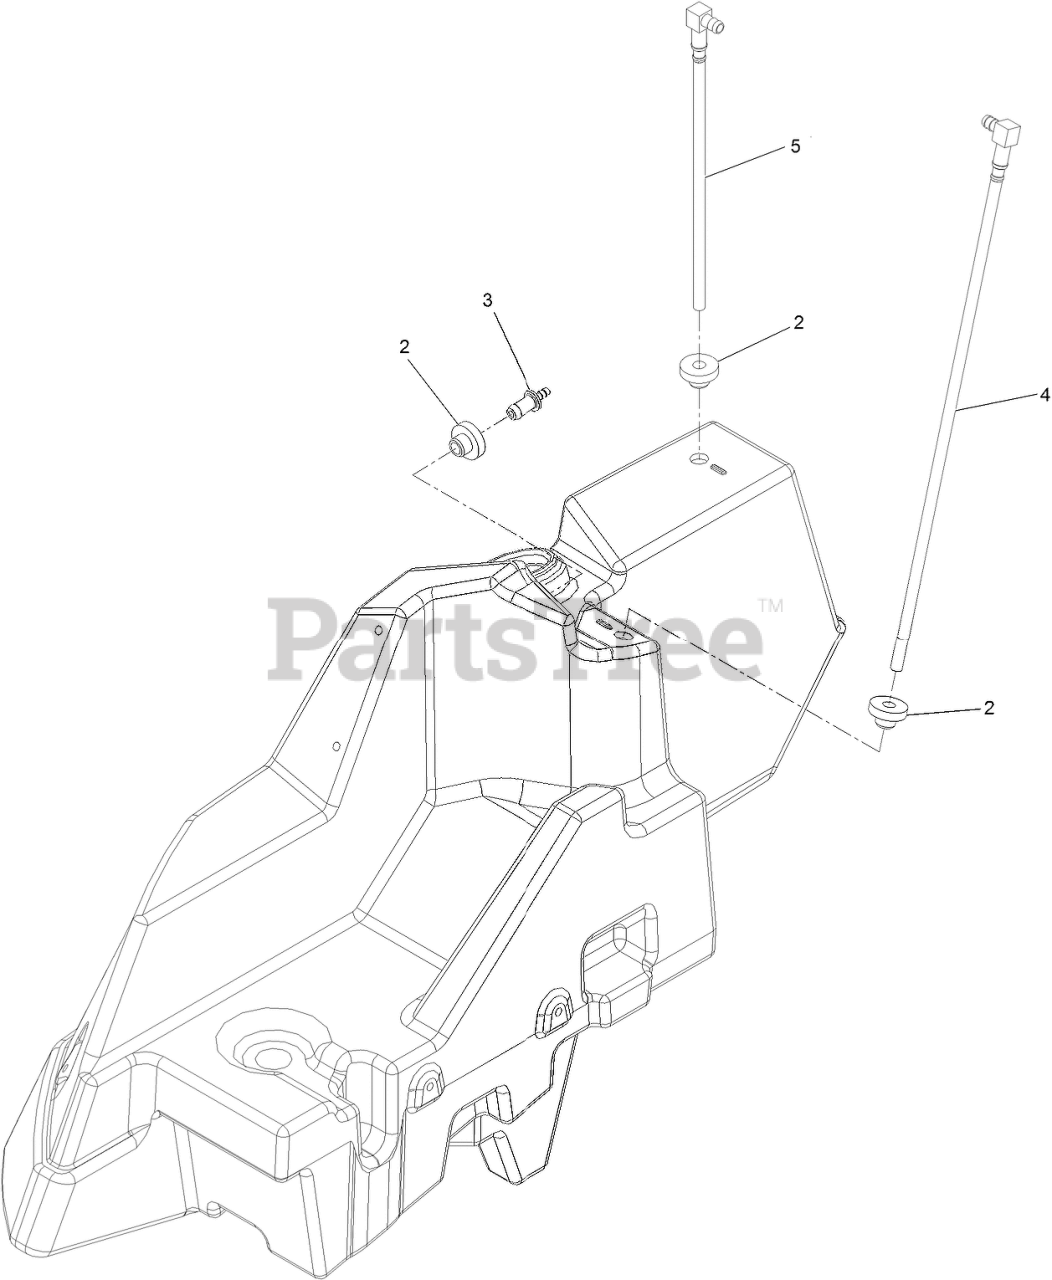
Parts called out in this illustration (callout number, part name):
2	BUSHING
3	FITTING-ORIFICE, STRAIGHT
4	PICK-UP-FUEL
5	RETURN-FUEL
